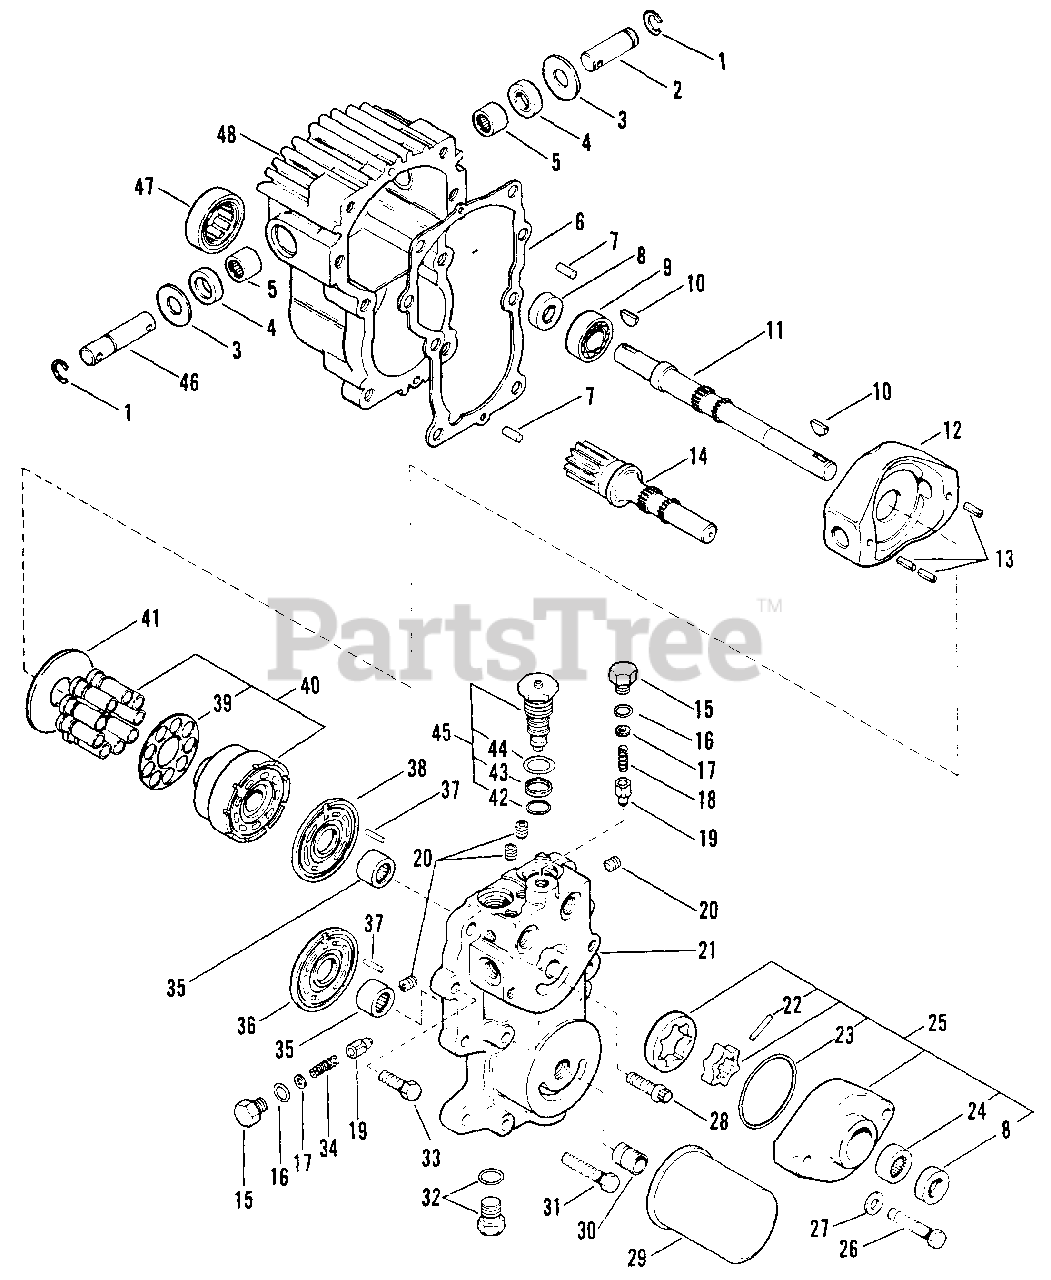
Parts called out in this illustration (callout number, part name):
1	Snap Ring, Ext. 11/16 SFT x .042
2	Trunnion Shaft
3	Washer, .694/.704 x 1.375 x .059
4	Lip Seal
5	Needle Brg, 11/16 I.D. x 7/8 O.D.
6	Gasket
7	Dowel Pin
8	Seal, 5/8 Nom. I.D.
9	Ball Bearing, 17 MM I.D. x 40 MM O.D.
10	Key, Woodruff .187 x .75 #9
11	Pump Shaft
12	Swashplate Variable
13	Pin, Spring 3/16 x 5/8
14	Motor Shaft
15	Plug, Hex Head
16	O-Ring, 7/16 Nom. I.D.
17	Shim Package
18	Spring, Compression
19	Relief Valve Cone
20	Pipe Plug
21	Center Section
22	Dowel Pin
23	O-Ring, 2-3/8 Nom. I.D.
24	Needle Brg, 5/8 I.D. x 7/8 O.D.
25	Charge Pump Kit
26	Screw, Cap 7/16-14 x 2 Gr. 2
27	Washer, .463/.473 x .390 x .108
28	Screw, Cap 3/8-16 x 1.25 Gr. 5
29	Oil Filter
30	Union
31	Bolt, Hex 3/8-16 x 2.00
32	Threaded Plug
33	Bolt, Hex 3/8-16 x 1.50
34	Spring, Charge Relief Valve
35	Roller Bearing, 17 MM I.D. x 15/16 O.D.
36	Motor Valve Plate
37	Dowel Pin
38	Pump Valve Plate
39	Slipper Retainer
40	Cylinder Block Kit
41	Thrust Plate
42	O-Ring
43	Back Up Ring
44	O-Ring
45	Check Valve Assembly
46	Trunnion Shaft
47	Roller Brg, 1-17/64 I.D. x 2-3/64 O.D.
48	Housing
